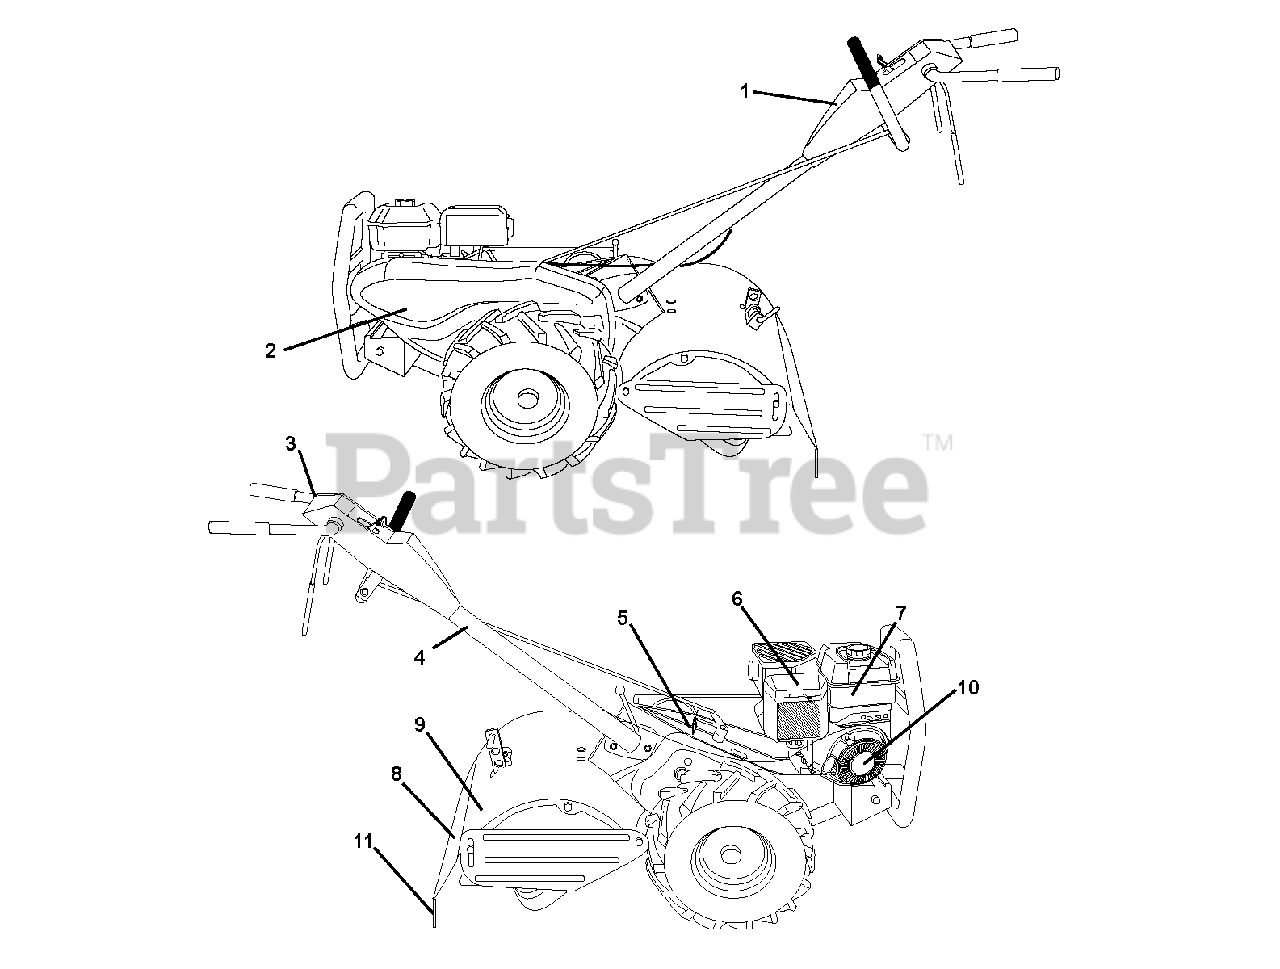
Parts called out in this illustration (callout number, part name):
5	DECAL.SHIFT.INDICATOR.TILLER
9	DECAL EUROPE STANDARD CE
10	DECAL, REWIND STARTER, B&S
